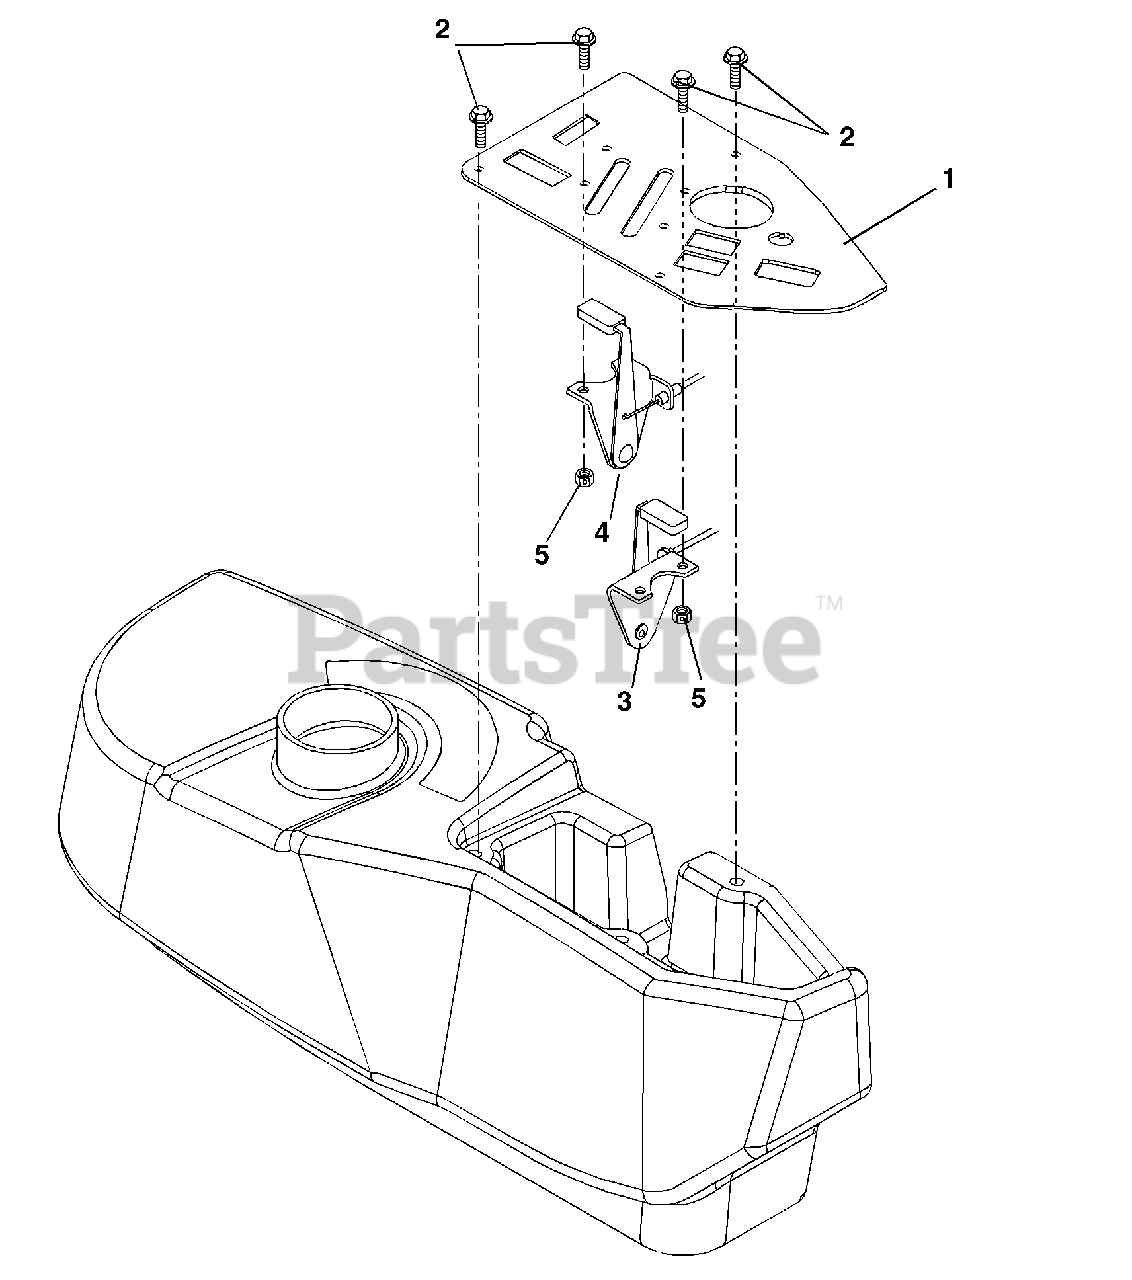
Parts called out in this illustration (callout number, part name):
1	Panel-Control
2	Screw-Machine 10-24 x .50 Hex Washer Head
3	Throttle, Control
3	Throttle, Control (Diesel)
4	Choke Control
5	Nut-Locking-Nylon 10-24 With Insert
